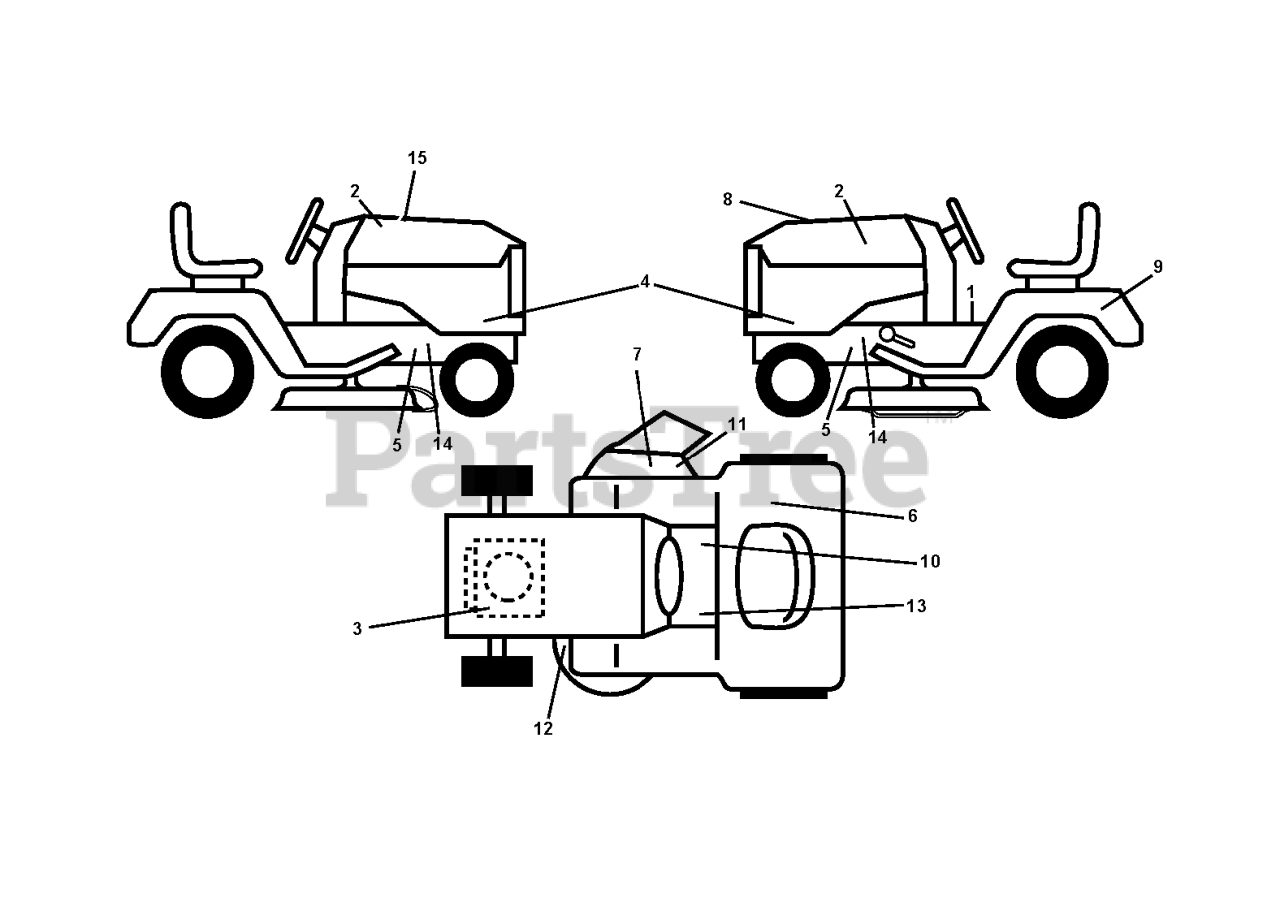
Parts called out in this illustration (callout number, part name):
1	LABEL
2	DECAL.HOOD.NAMELOGO.HUSQ
3	DECAL
6	Decal, Fender 100 DB/CE
7	DECAL.INTERNATIONL.CUTFINGER
8	DECAL.WHEEL.STRG.LGN.H
9	DECAL BTRY SYMBOLS
10	DECAL PARK BRAKE
11	DECAL, DEFLECT WARNING
12	DECAL.V-BELT.SCHEMATIC.36/38/9
13	DECAL
